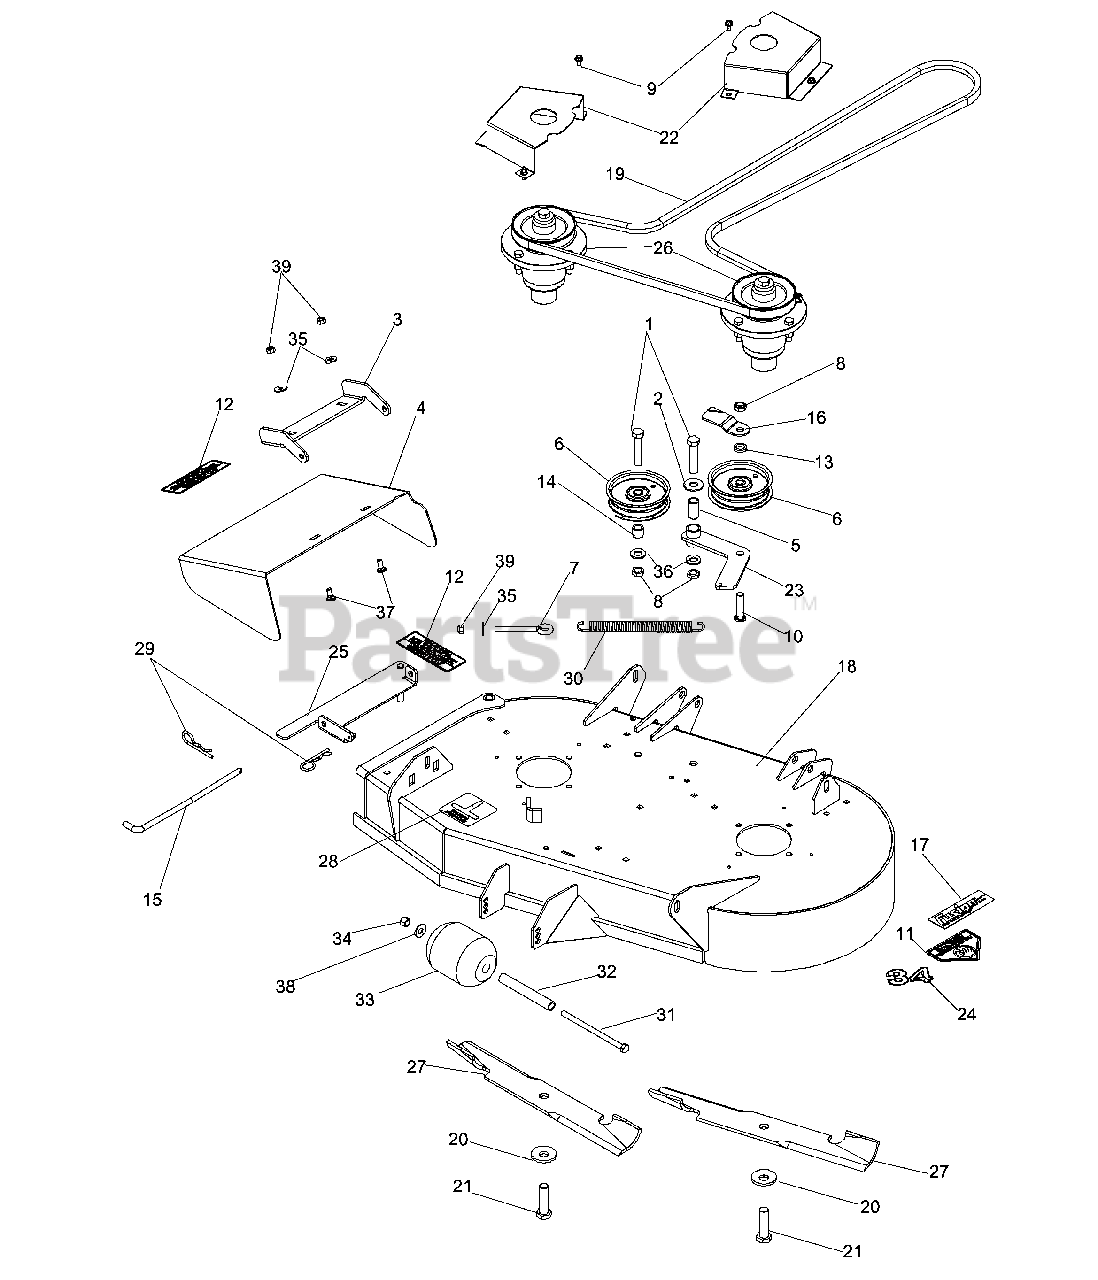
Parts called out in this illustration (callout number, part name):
1	HEX SCREW 1/2-13 X 2.5" GR 5
2	WASH USS FLAT 1/2
3	HINGE - 34, 44 BLUE
4	CHUTE - 34 BLACKBEAR, BLUE
5	BUSHING DIXON 1080
6	PULLEY IDLER
7	EYE BOLT 5/16 X 3.50
8	NUT, 1/2-13 THIN PROF NYL
9	1/4-20 X 1/2 HWH FORM SCR H
10	STUD 1/2-13 X 2
11	WARNING LABEL DANGER
12	DECAL, DANGER
13	HD PULLEY SPACER
14	BUSHING
15	DEFLECTOR PIN
16	BELT GUARD BLK
17	DECAL, FUSION
18	DECK W/DECALS
20	BLADE WASHER
21	BLADE BOLT
22	PULLEY GUARD 34
23	IDLER ARM WLDT., BLACK
24	DECK DECAL 34`
25	DEFLECTOR MT. WLDT.
26	SPINDLE ASM.
27	BLD 34 HI-LIFT FUSION
28	DECAL, BELT ROUTING
29	5/32 X 3.0 HAIR PIN COTT
30	SPRING, DECK BELT
31	BOLT 3/8 X 6 GR5
32	BUSHING
33	ROLLER 3-3/4 DIA. X 4-1
34	NUT 3/8-16 NYLOC
35	FLAT WASHER 5/16 SAE
36	WASHER 1/2" FLAT
37	BOLT 5/16C X 3/4" CARRIAGE
38	WASHER 3/8 FLAT
39	NUT 5/16 NYLOC
40	HEX SCREW 1/2-13 X 2.5" GR 5
41	NUT 1/2-13 HEX NYLOC ZD
